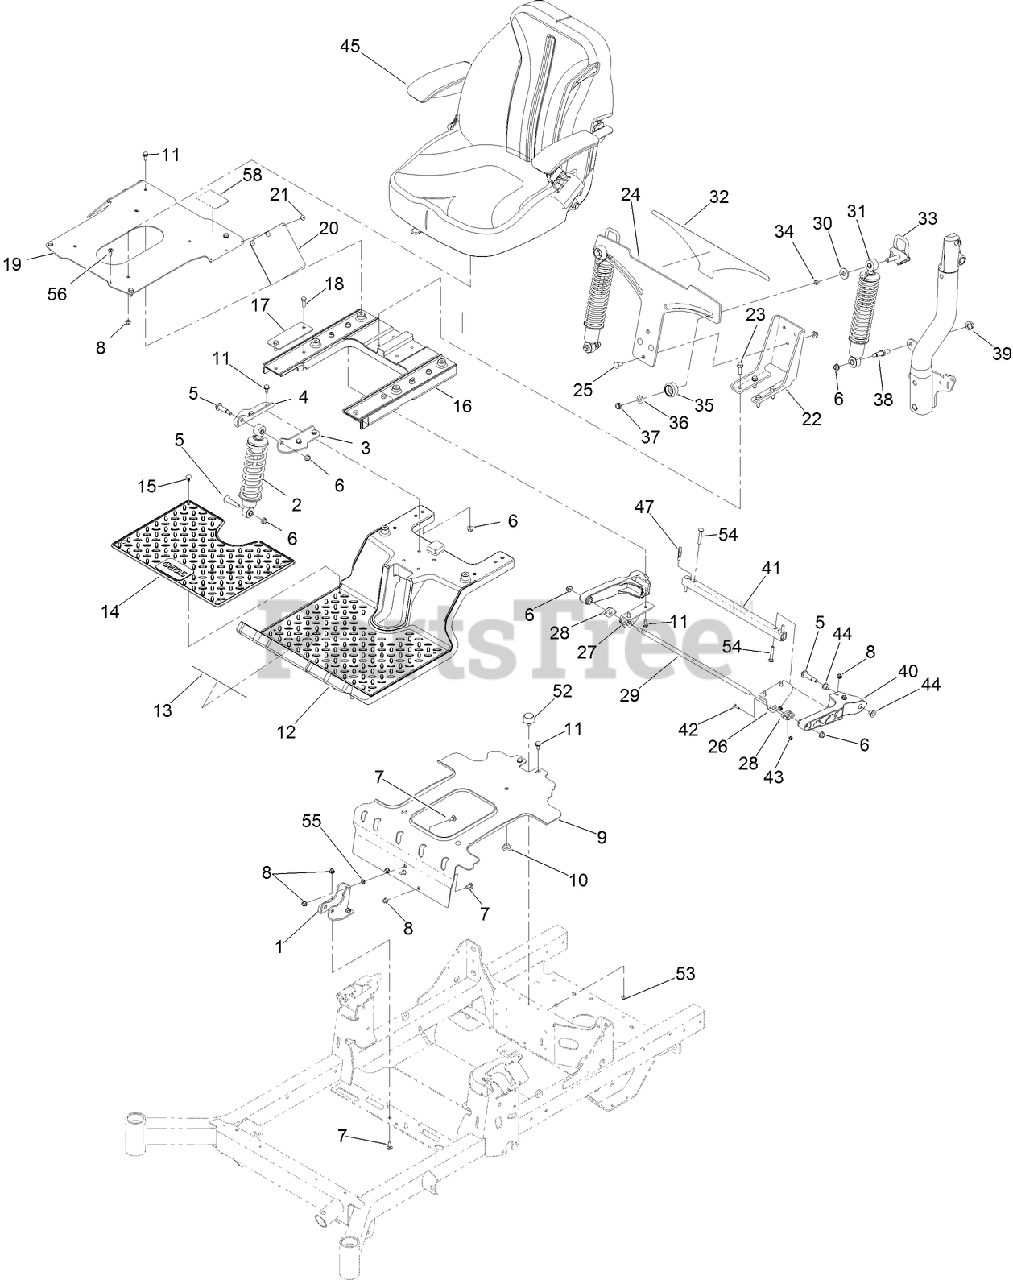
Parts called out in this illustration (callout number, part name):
1	BRACKET-SHOCK, FRONT LOWER
2	SHOCK/SPRING
3	BRACKET-SHOCK MOUNT, UPPER (LH)
4	BRACKET-SHOCK MOUNT, UPPER (RH)
5	BOLT-SHOULDER, HWH
6	NUT-HF, NI
7	SCREW-CARR
8	NUT-HF, NI
9	BRACKET-TANK
10	BUMPER-SEAT
11	SCREW-HWHTF
12	SUBFRAME-FRONT
13	DECAL-DANGER
14	FLOORMAT
15	PLUG-PLASTIC
16	SUBFRAME-REAR
17	PLATE-BACKER
18	SCREW-HH
19	PLATE-SEAT
20	FLAP-RUBBER
21	RIVET-POP
22	BRACKET-MOUNT, LOWER
23	SCREW-THD
24	PLATE-MOUNTING, ADJ SHOCK
25	SCREW-CARR
26	BRACKET-ARM, TRAILING (LH)
27	BRACKET-ARM, TRAILING (RH)
28	BEARING-FLANGE
29	ROD-PIVOT
30	WASHER-PLASTIC
31	SHOCK/SPRING ASM
32	DECAL-MYRIDE
33	CAM LOCK ASM
34	BEARING-SLEEVE
35	KNOB-LOCK, CAM
36	WASHER-ADJUSTING
37	NUT-HEX
38	BOLT-SHOULDER
39	NUT-LOCK
40	TRAILING ARM
41	TUBE-ARM, TRAILING
42	SCREW-CARR
43	NUT-HF
44	BUSHING-FLANGE
45	SEAT ASM
47	CLAMP-HOSE
52	BUMPER
53	NUT-HF
54	BOLT-CARR
55	NUT-PUSH
56	SCREW-SHOULDER
58	DECAL-AID, SERVICE
